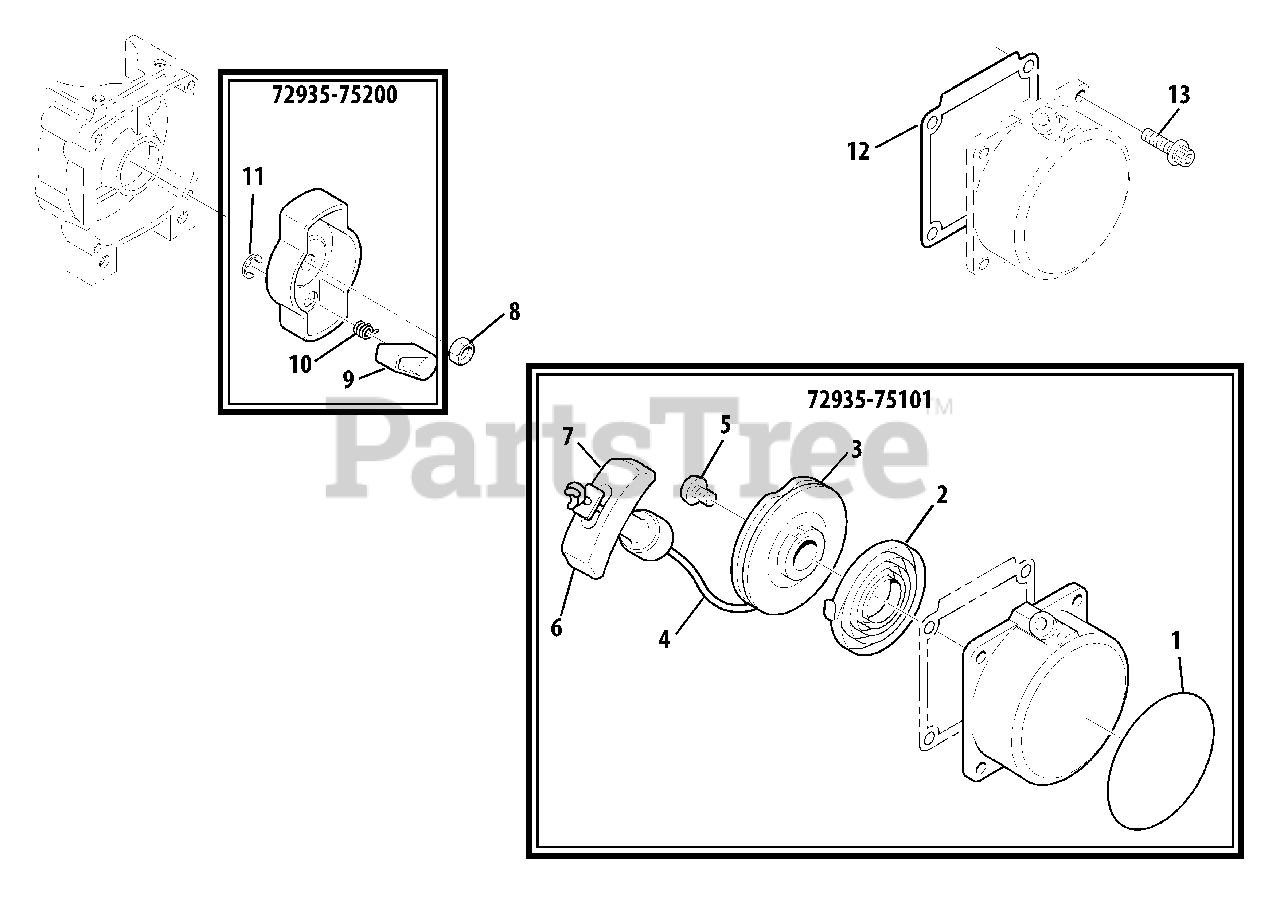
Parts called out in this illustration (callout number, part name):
1	LABEL - SHINDAIWA PROFESSIONAL
2	SPRING
3	REEL, ROPE
4	ROPE
5	SCREW -- TAPPING
6	GRIP, STARTER
7	RETAINER, ROPE
8	NUT
9	PAWL, STARTER
10	SPRING, RETURN
11	RING, RETAINING
12	GASKET
13	SCREW - 4X16
72935-75101	STARTER ASSY
72935-75200	STARTER PAWL ASSY
